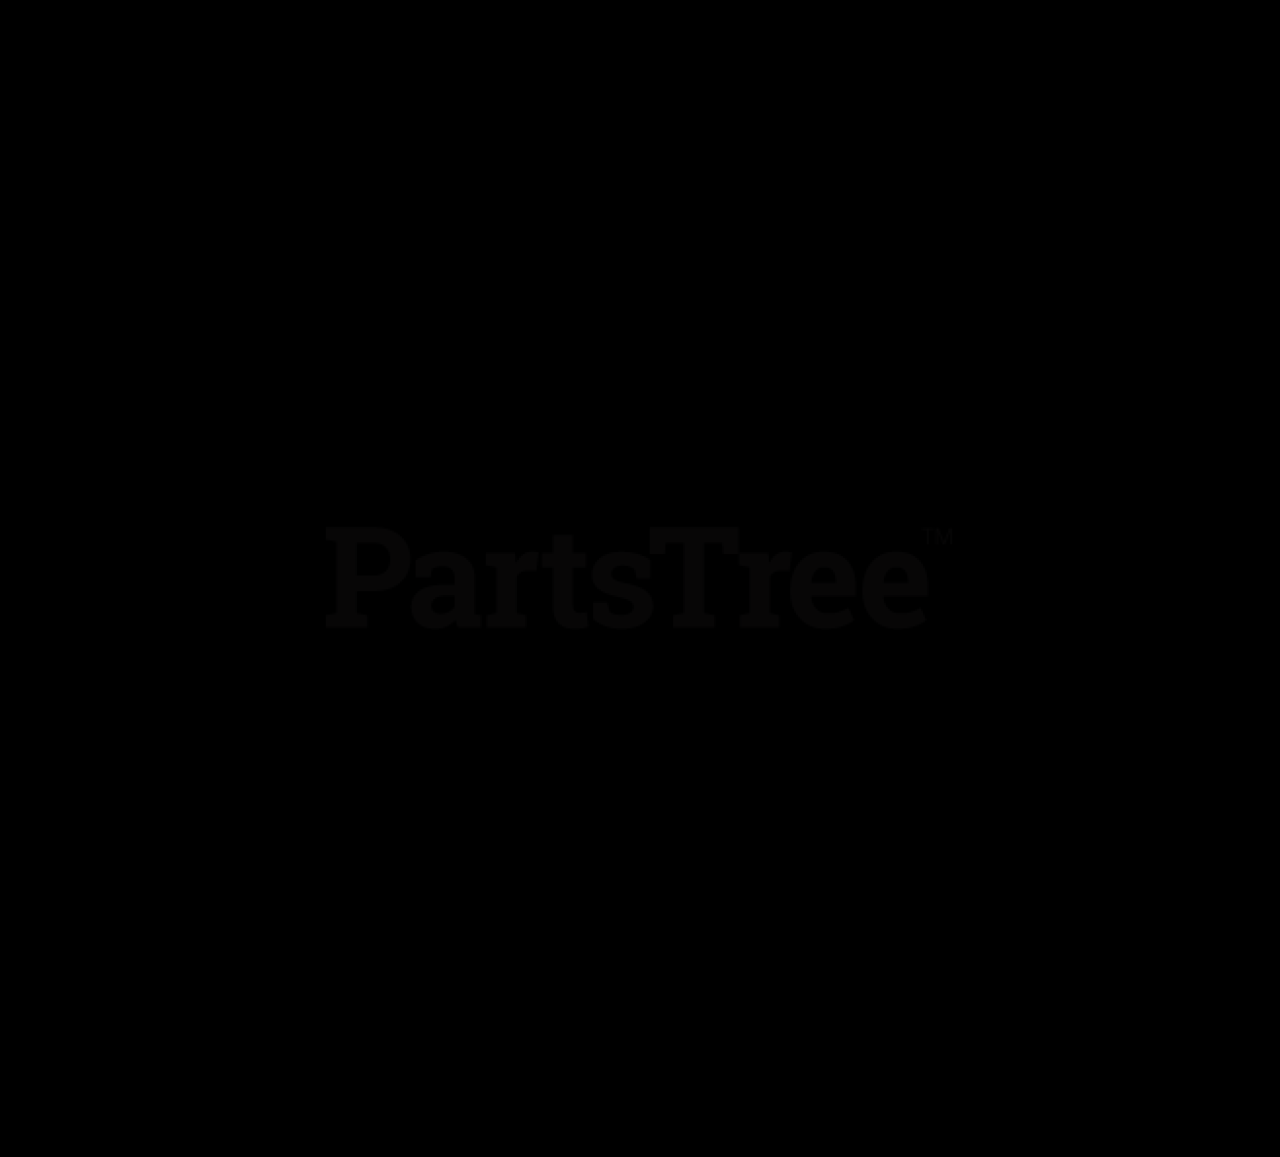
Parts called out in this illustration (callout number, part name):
1	Decal, Lift Lever
2	Decal, 60" (992215, 218)
3	Decal, Parking Brake Lever
4	Decal, Maintenance Instructions
5	Decal, Diesel Control Panel
6	Decal, Height of Cut
7	Decal, Belt Diagram (992215, 216)
8	Decal, Pro-Master 260 (992215, 218)
9	Decal, Gravely Heritage – Large
10	Decal, Pinch Point
11	Decal, Seat Release
12	Decal, X-Factor Deck
